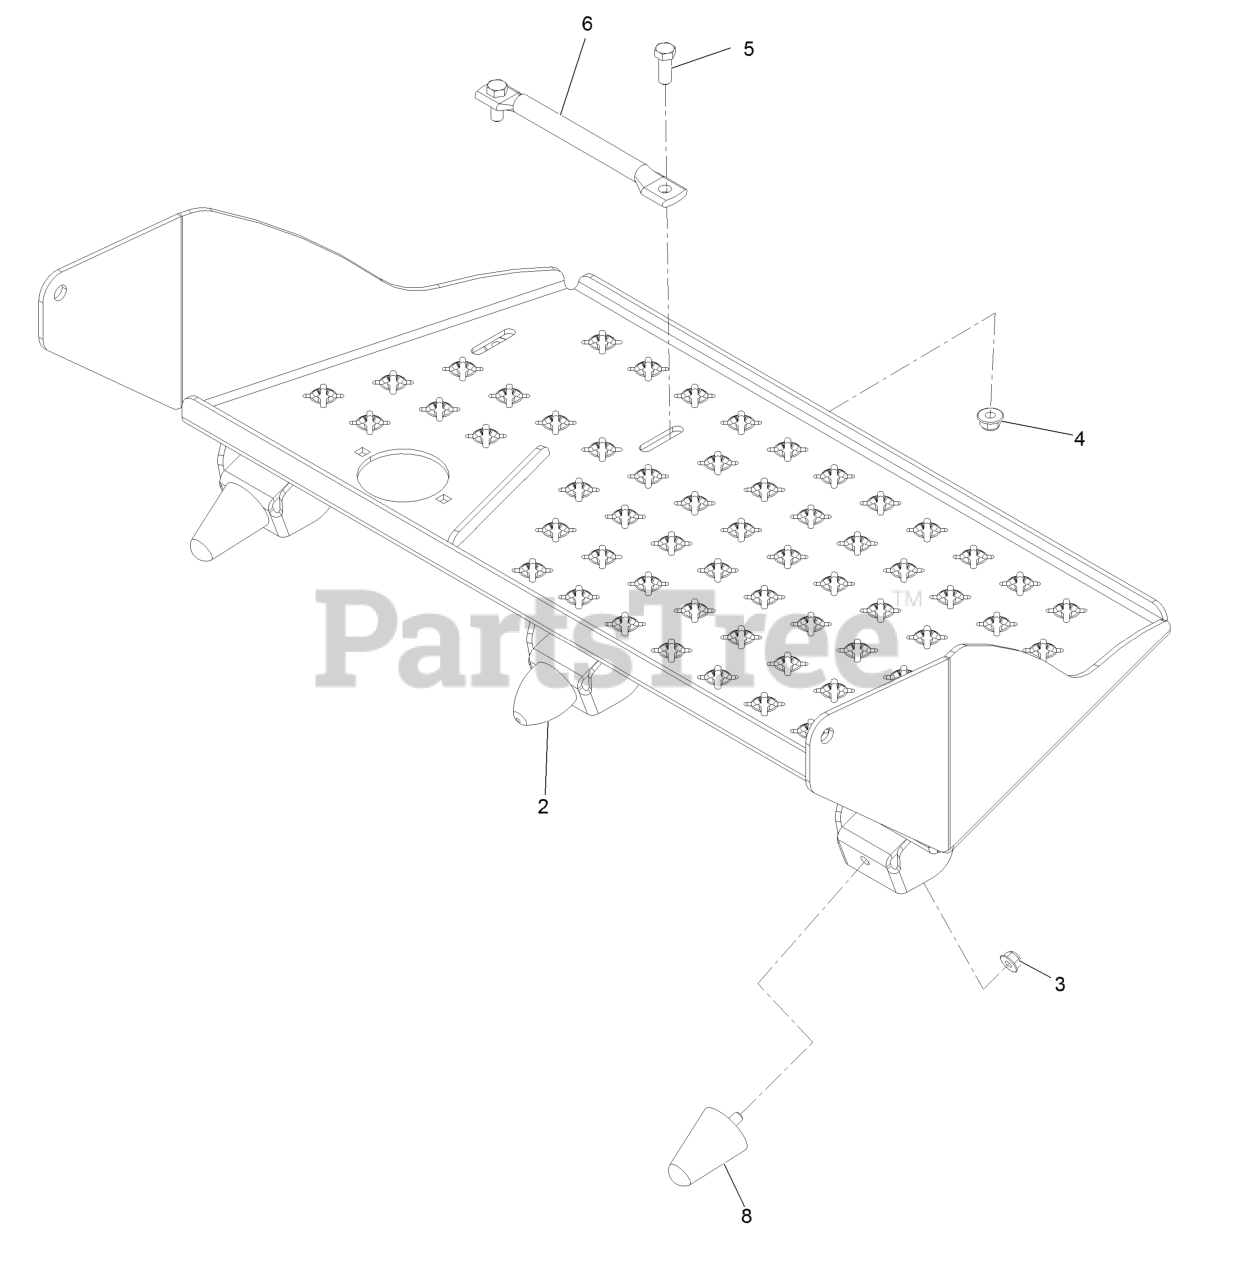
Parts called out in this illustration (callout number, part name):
2	Bumper-Rubber
3	Nut-Nyloc 5/16-18 Flg
4	Nut-Nyloc 3/8-16 Flg
5	Screw-HH 3/8-16 X 1
6	Rocker-Foot Pedal
8	Bumper-Rubber
